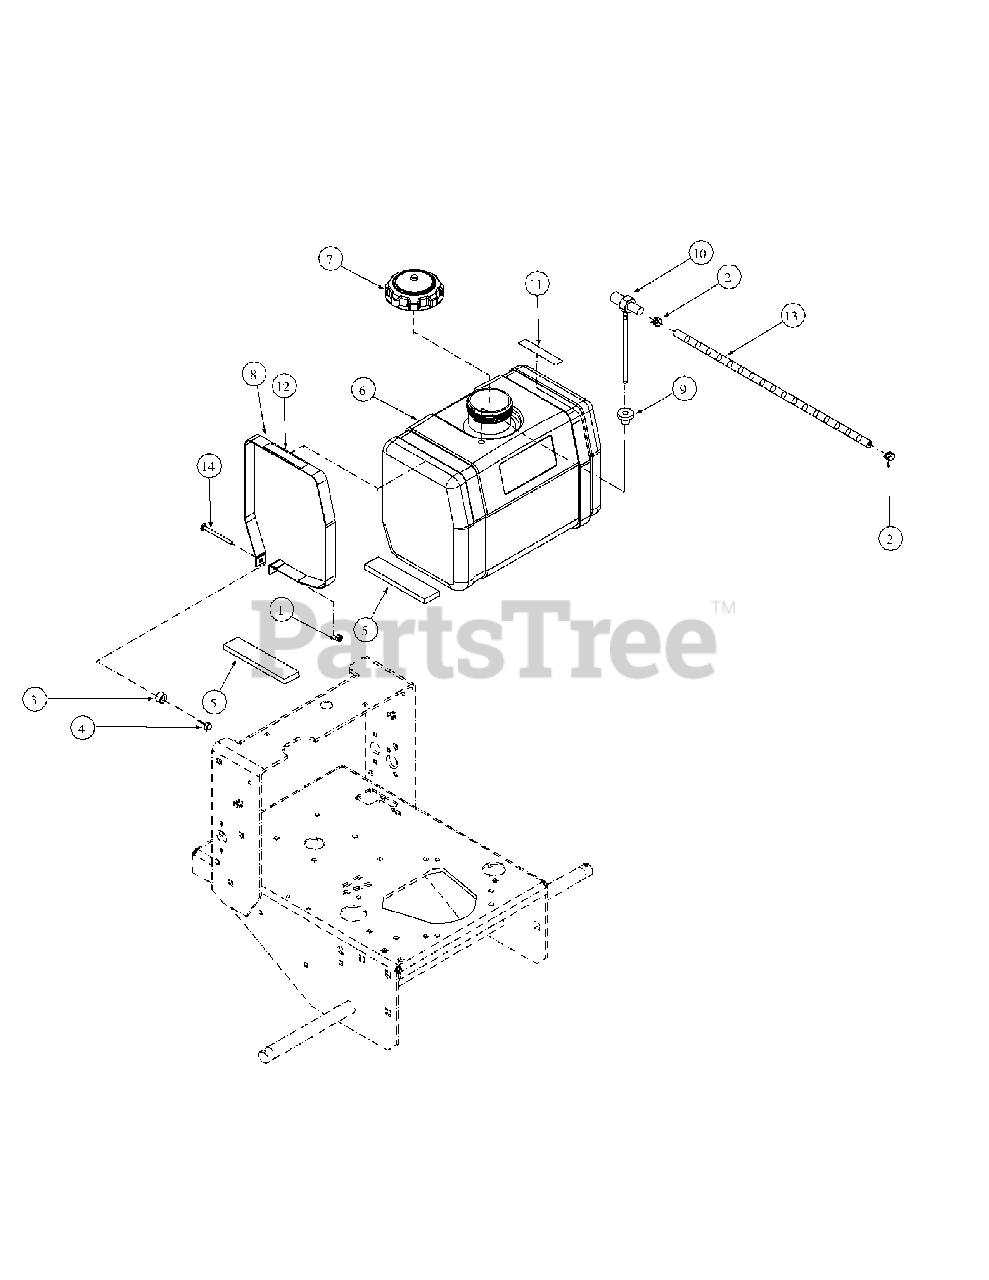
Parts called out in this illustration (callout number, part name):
1	Lock Nut, Nylon Insert, 1/4-20
2	Uni-Clamp
4	Nut, 1/4-20
5	Rubber Stop Pad
6	Fuel Tank
7	Fuel Cap, 3.5
8	Fuel Tank Strap
9	Grommet Fuel Tank
10	Shut Off Fuel Tank
11	Label, Mower Warning Turn Off Engine
12	Label, Mower Instruction, Fuel Valve
13	Hose Fuel, 22" x .25 ID
14	Carriage Bolt, 1/4-20 x 3.00
